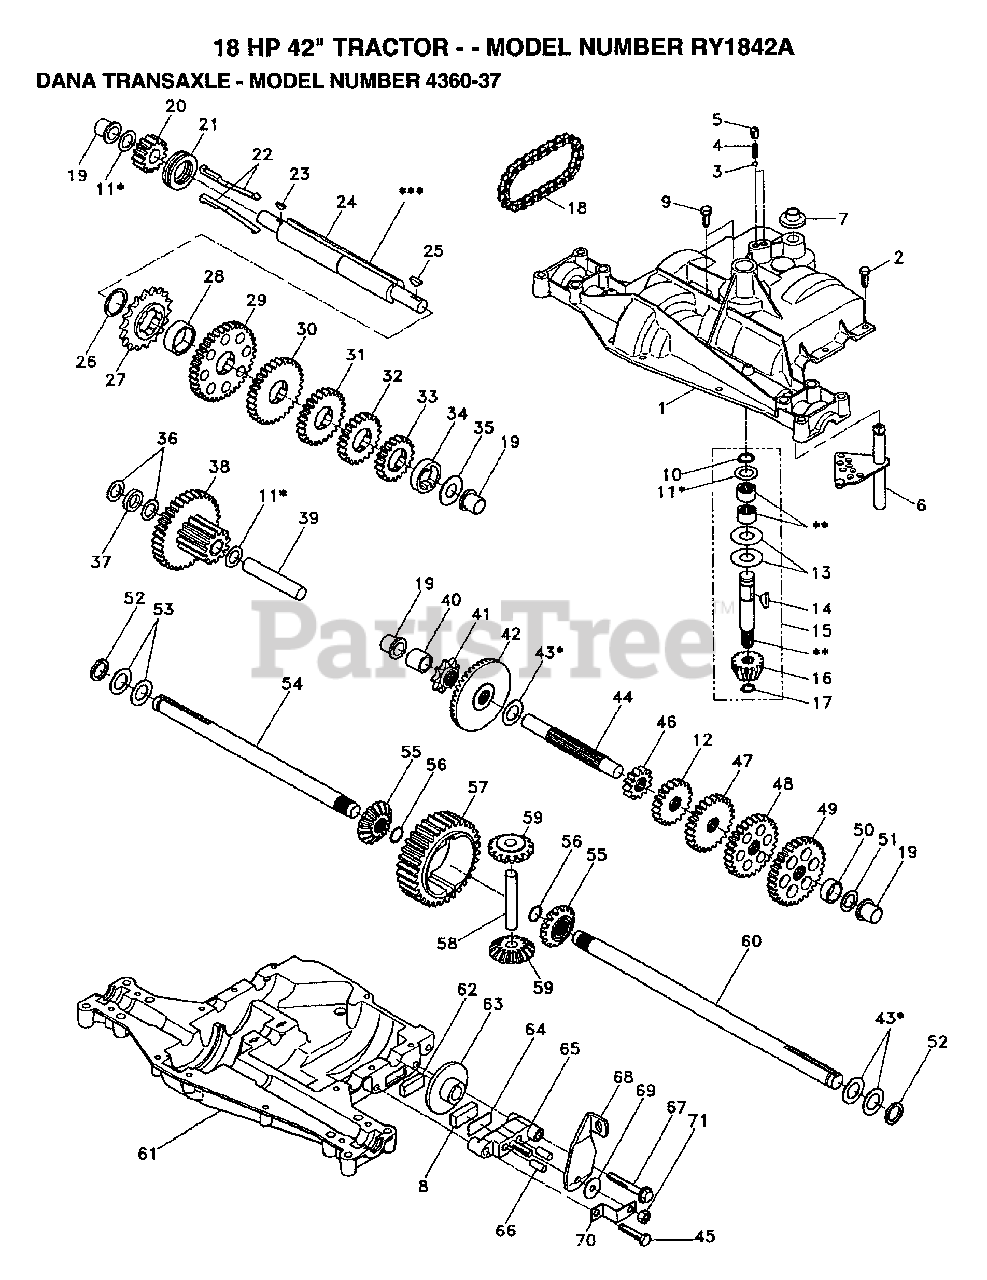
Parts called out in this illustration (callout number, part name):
1	HOUSING UPPER
3	BALL, DETENT
4	SPRING, DETENT
5	SCREW, SET
6	KIT SHIFTER ASSY
7	BOOT, SHIFTER
8	PUCK, FRICTION
9	SCREW TAPPING WITH SEALER
10	RING RETAINING
11	ASSY, KIT, SHIM .625 SHAFT
12	GEAR SPUR, 15 TEETH
13	WASHER, PLAIN .632 X 1.38 X .046
14	KEY WOODRUFF #9
15	ASSY KIT INPUT SHAFT
16	PINION BEVEL 14 TEETH
17	RING, RETAINING
18	CHAIN, 24 PITCHES
19	BEARING, FLANGE
20	GEAR SPUR, 14 TEETH
21	COLLAR CLUTCH
22	KEY CLUTCH
23	KEY WOODRUFF #3
24	SHAFT INTERMEDIATE
25	KEY, WOODRUFF, #61
26	RING, RETAINING
27	SPROCKET, 18 TEETH
29	GEAR, SPUR, 37 TEETH
30	GEAR, SPUR, 35 TEETH
31	GEAR, SPUR, 30 TEETH
32	GEAR, SPUR, 25 TEETH
33	GEAR, SPUR, 22 TEETH
34	GEAR, SPUR, 19 TEETH
35	WASHER, PLAIN .640 X 1.37 X .061
36	WASHER, PLAIN .632 X 1.00 X .026
37	SPACER .630 X 1.00 X .169
38	ASSY GEAR COMB 12&35 TEETH
39	SHAFT, IDLER
40	SPACER .635 X .875 X .755
41	SPROCKET, 9 TEETH
42	GEAR, BEVEL, 42 TEETH
43	ASSY, KIT, SHIM .750 SHAFT
44	SHAFT, DRIVE
45	SCREW TAPPING
46	GEAR, SPUR, 12 TEETH
47	GEAR, SPUR, 20 TEETH
48	GEAR, SPUR, 25 TEETH
49	GEAR, SPUR, 28 TEETH
50	GEAR, SPUR, 31 TEETH
51	WASHER, PLAIN .632 X 1.00 X .060
52	WASHER, NEOPRENE
53	WASHER, PLAIN .758 X 1.25 X .031
54	AXLE LEFT HAND
55	GEAR MITER 15 TEETH
56	RING, RETAINING
57	GEAR, SPUR, 32 TEETH
58	SHAFT, CROSS
59	GEAR, MITER, 15 TEETH
60	AXLE, R.H.
61	HOUSING LOWER
62	PUCK, FRICTION
63	DISC, BRAKE
65	JAW, BRAKE
66	PIN, DOWEL
67	SCREW, SELF-TAPPING
68	LEVER, ACTUATING
69	WASHER, PLAIN .321 X 1.00 X .055
70	BRACKET, ANTI-ROTATION
71	LOCKNUT 5/16-24
